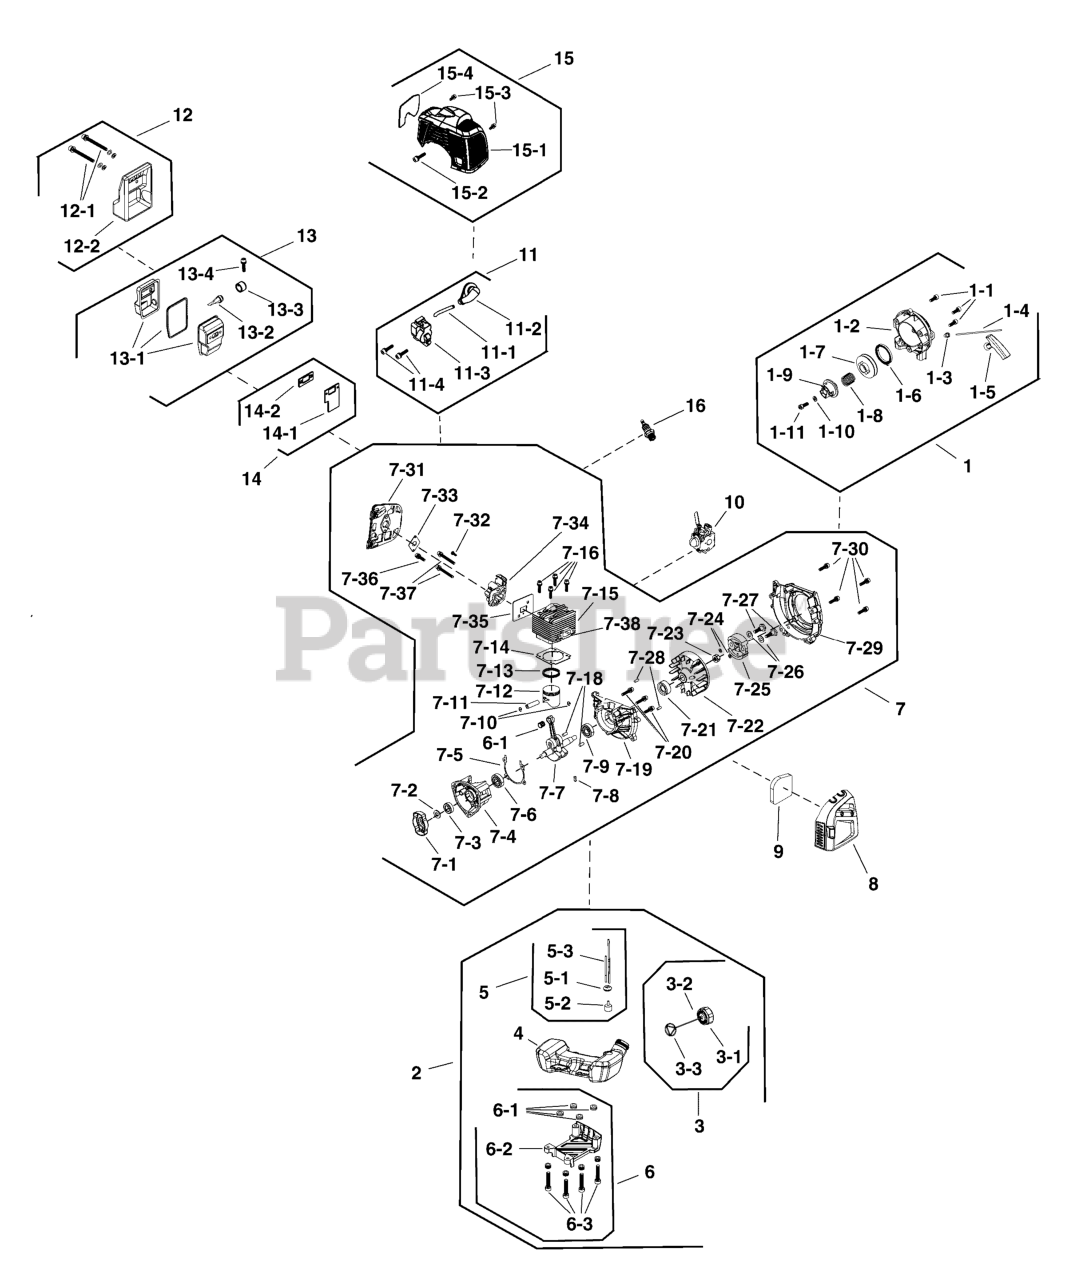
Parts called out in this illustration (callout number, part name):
1	STARTER ASSEMBLY
1-2	STARTER HOUSING
1-3	GROMMET, Eyelet
1-5	HANDLE
1-6	COIL SPRING
1-7	STARTER PULLEY
1-8	SPRING
1-9	RATCHET WHEEL
2	FUEL TANK ASSEMBLY
3	FUEL CAP ASSEMBLY
3-1	FUEL CAP
3-2	O RING
3-3	FUEL CAP LOCK
4	FUEL TANK
5	FUEL FILTER ASSEMBLY
5-1	BALANCER, FUEL FILTER
5-2	FUEL FILTER
5-3	FUEL FILTER PIPING
6	FUEL TANK BASE ASSEMBLY
6-1	RUBBER DAMPENER
6-2	BASE, FUEL TANK
7	25.4CC SHORT BLOCK ASSEMBLY
7-1	START REEL
7-4	CRANK CASE HOUSING RH
7-5	GASKET CRANK CASE
7-7	CRANK SHAFT ASSEMBLY
7-10	CIRCLIP
7-11	PISTON PIN
7-12	PISTON
7-13	PISTON RING
7-14	GASKET CYLINDER
7-15	CYLINDER
7-19	CRANK CASE LH
7-22	MAGNETO ROTOR
7-24	FLAT WASHER
7-25	CLUTCH ASSEMBLY
7-27	BOLT
7-29	FLYWHEEL COVER
7-31	AIR FILTER BASE
7-33	GASKET MANIFOLD
7-34	MANIFOLD
7-35	PRESSURE PLATE
7-38	GASKET CARBURETOR
8	AIR FILTER COVER
9	FOAM AIR FILTER
10	CARBURETOR ASSEMBLY
11	IGNITION COIL ASSEMBLY
11-1	WIRING HARNESS ASSEMBLY
11-2	SPARK PLUG COVER ASSEMBLY
11-3	IGNITION COIL ASSEMBLY
12	MUFFLER HOUSING COVER ASSEMBLY
12-2	MUFFLER HOUSING COVER
13	MUFFLER ASSEMBLY
13-1	MUFFLER, NO CAT CONVERTER
13-2	SPARK ARRESTOR MESH
13-3	SEAL
14	MUFFLER GASKET ASSEMBLY
14-1	INNER GASKET MUFFLER
14-2	OUTER GASKET MUFFLER
15	ENGINE TOP COVER, BLACK
15-1	TRIMMER TOP HOUSING
15-4	REFLECTIVE THERMAL GASKET
16	SPARK PLUG
